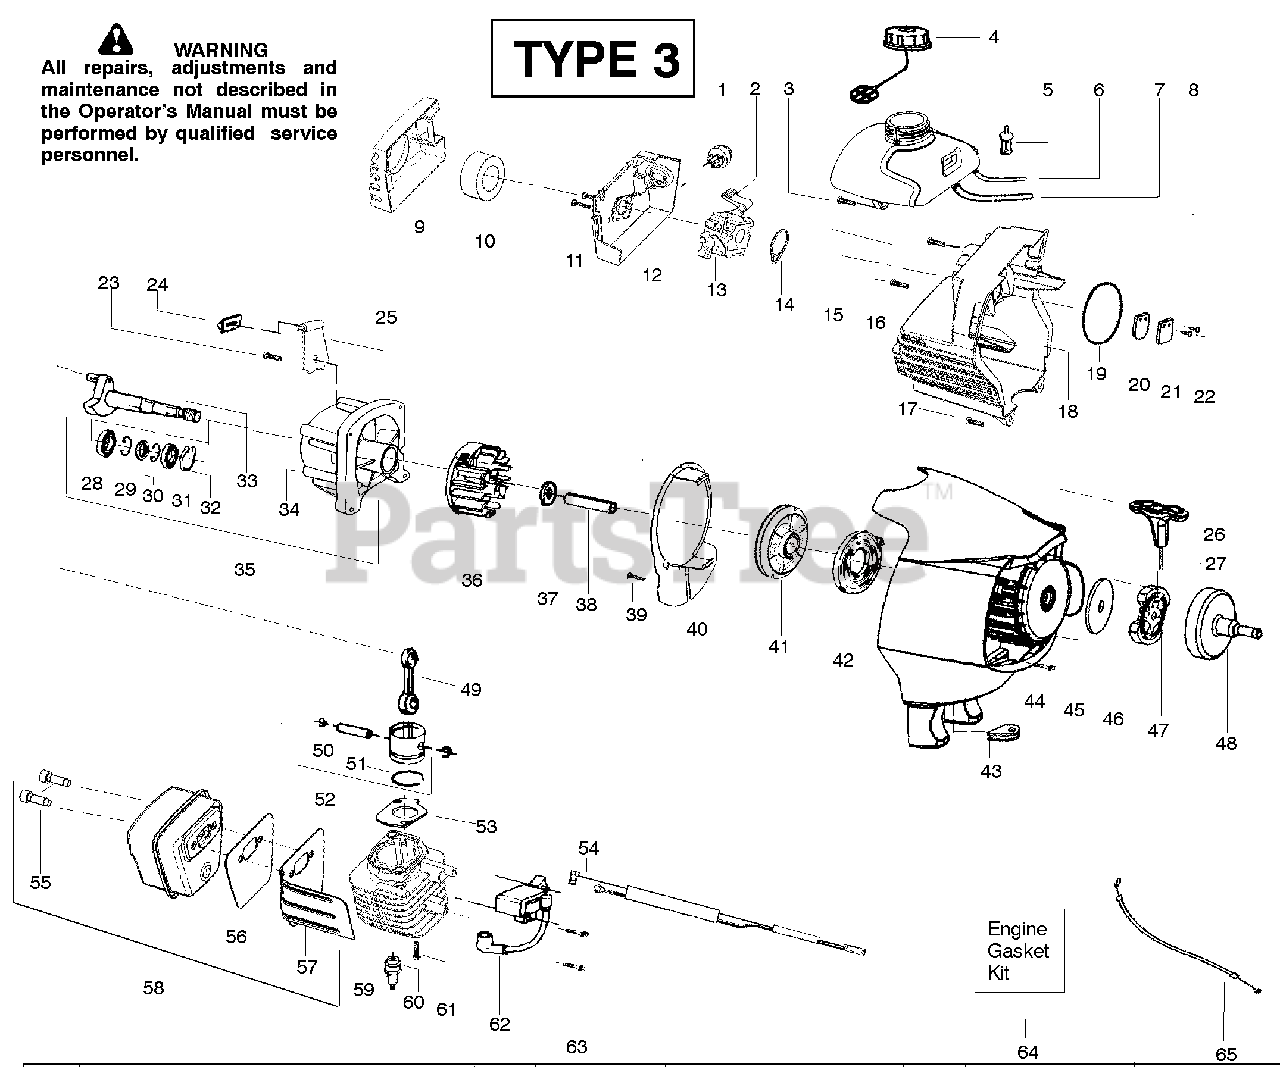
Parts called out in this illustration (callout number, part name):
2	Kit-Choke Lever
3	Bulb-Purge
3	Screw-tank
4	Cap-Fuel w/ret.
5	Assy-Fuel pickup
6	Kit-Fuel line
7	Kit-Fuel/Purge line
9	Cover-Air box
10	Filter-Air
11	Screw-Carb.
13	Kit-Carb assy. (C1U-W32)
14	Seal-Carb.(kit)
15	Assy-Fuel Tank
16	Screw-Crankcase
17	Screw-Shroud
18	Assy-Rear Shroud
19	O-ring-Shroud (kit)
20	Valve-Reed
21	Stop-Reed
22	Screw-Reed stop
23	Screw-Retainer
24	Isolator-Tank
25	Ret.-Tank
26	Handle-Starter
27	Kit-Rope
28	Bearing-Inner
29	Retainer
31	Bearing-Outer
32	Ret.-Crankshaft
33	Assy-Crankshaft
34	Assy-Crankcase
35	Assy-C'case/C'shaft
36	Assy-Flywheel
39	Screw-Baffle
40	Plate-Baffle
41	Kit-Pulley
42	Spring-Starter
44	Screw-F/hsg.
45	Assy-Fan Housing
46	Washer-Clutch
47	Assy-Clutch
48	Assy-Drum/Adapter
49	Assy-Conn. Rod
50	Ret.-Piston pin
51	Ring-Piston
52	Kit-Piston
53	Gasket-Cylinder(kit)
54	Assy-Leadwire
55	Bolt-Muffler 1/4"-20
56	Gasket-Muffler (kit)
58	Kit-Muffler
59	Cylinder
60	Plug-Spark(RCJ-6Y)
61	Bolt-Cyl. 1/4"-20
62	Module-Ignition
63	Screw-Module
64	Kit-Gasket/Seal
65	Assy-Throttle cable
